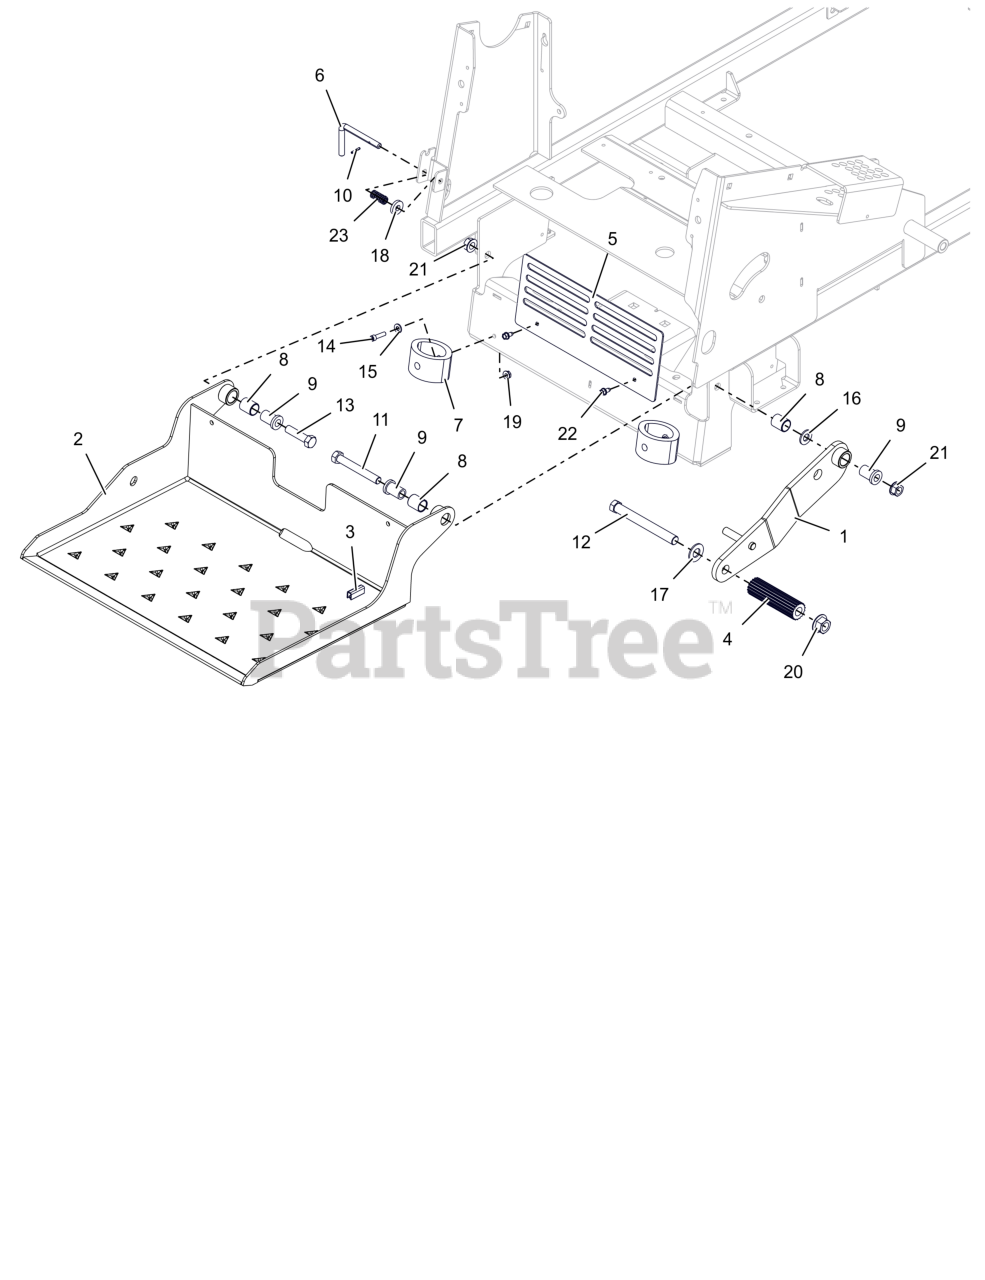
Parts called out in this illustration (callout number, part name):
1	BRKT, DECK LIFT FOOT PEDDLE
2	WLDMT, OPERATOR PLATFORM (BLACK)
3	STRIP, COWL
4	ROD, FOOT PEDAL (BLACK)
5	GUARD, FOOT (RED)
6	PIN, PLATFORM LOCK
7	BUMPER, PLATFORM
8	BRG, .750 X .875 X 1.000
9	BSHG-FLG .515X.746X1.290X1.000
10	PIN-ROLL .125X.75
11	BLT,HEX .50-13X3.75 G5 ZCC
12	BLT, HEX .62-11X5.50 G5 FBP
13	BLT, HEX .50-13X2.00 G5 ZCC
14	SCR, SKH .25-20X1.00
15	WSHR,FLT .281X.625X.065 ZCC
16	WSHR,FLT .531X1.062X.095 ZCC
17	WSHRFLT 5/8SAE CARBHARD FBP
18	WSHR, FLT .406X1.00X.188 ZCC
19	NUT-LK-CTR-FLG .25-20 ZC120
20	NUT,FLG-TOP LK .625-11 FBP
21	NUT-LK-CTR-FLG .500-13 GG ZCC
22	SCR-TAP .25-20X.50 HWH ZCC
23	SPRING, COMPRESSION
